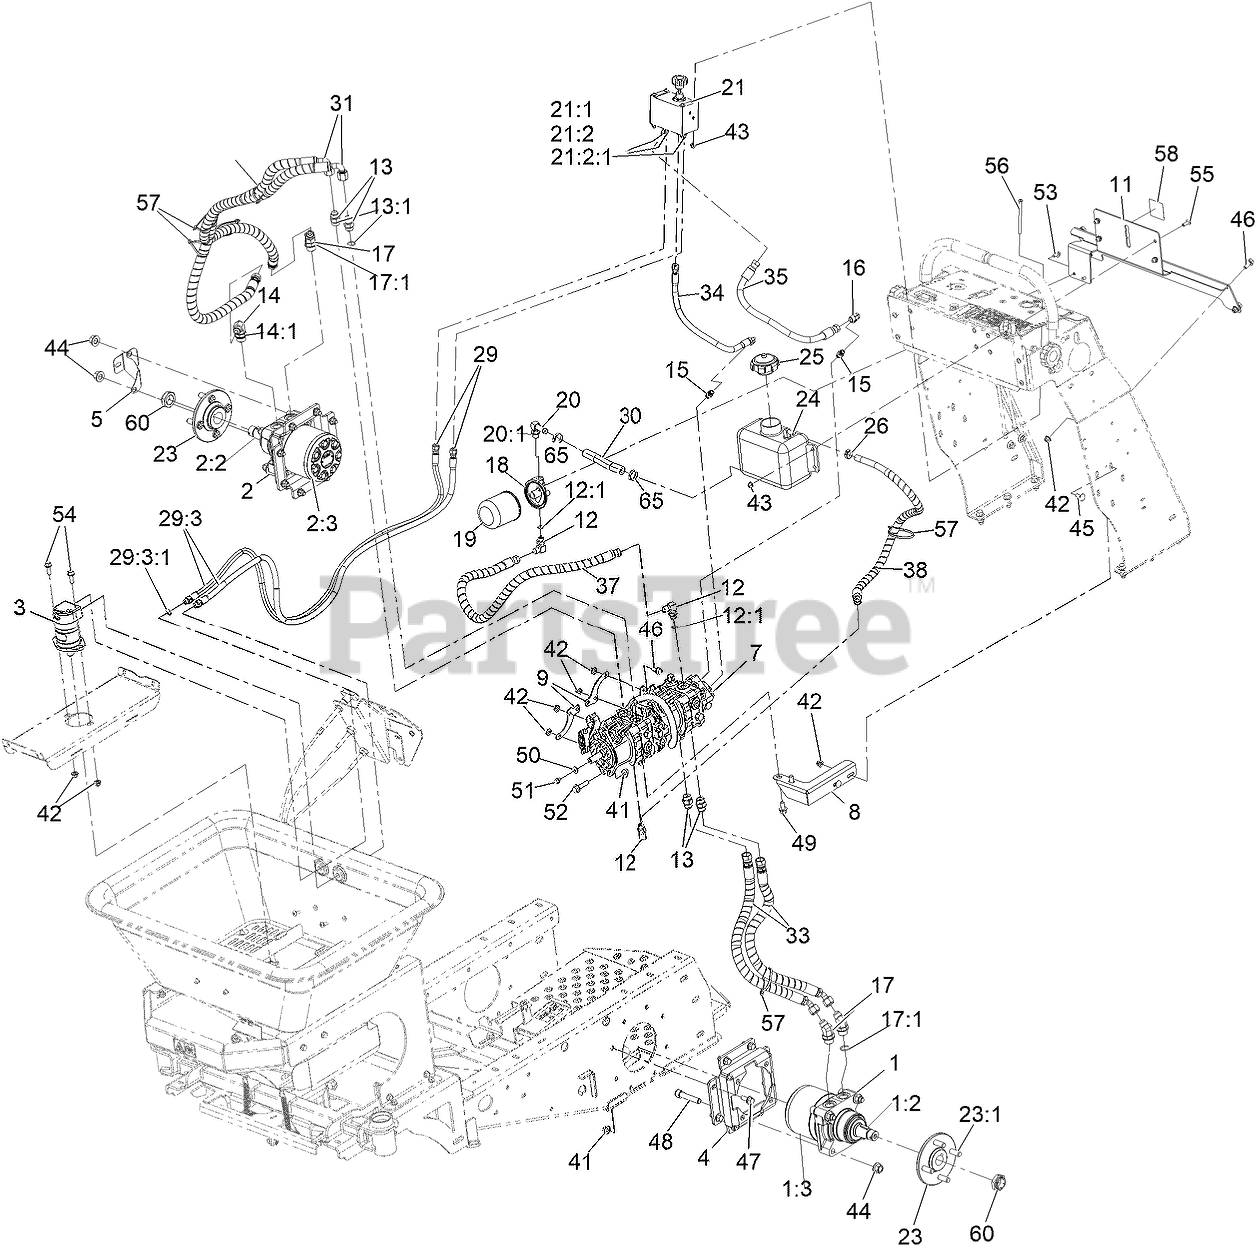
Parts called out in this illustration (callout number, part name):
1	MOTOR, LH WHEEL
1:2	KEY-WOODRUFF
1:3	SEAL KIT
2	MOTOR, RH WHEEL
2:2	KEY-WOODRUFF
2:3	SEAL KIT
3	MOTOR-HYDRAULIC, SPREADER
4	Mount-Motor, Wheel
5	BRACKET-HOPPER, SPEEDOMET
7	PUMP-TANDEM
8	Bracket-Support, Hydro Pump
9	Extension, Hydro Pump
11	Mount, Hydraulic Tank And Filter
12	FITTING-ELBOW, 90 DEG
12:1	O-RING
13	FITTING-STRAIGHT
13:1	O-RING
14	FITTING-90 DEG
14:1	O-RING
15	FITTING-STRAIGHT
16	FITTING-90 SWIVEL
17	FITTING-ELBOW, 45 DEG
17:1	O-RING
18	HEAD-FILTER
19	FILTER-25 MICRON, BI-DIRECTIONAL
20	FITTING-ELBOW, 90
20:1	O-RING
21	Manifold-Flow Control, Hopper
21:2	FITTING-ELBOW, 45 DEG
21:2:1	O-RING
23	HUB-WHEEL
23:1	STUD-1/2-20 X 1.55
24	TANK-HYDRAULIC, PLASTIC
25	Cap-Vented
26	CLAMP-OETIKER, 167
29	HOSE ASM-HYD HP
29:3	Fitting-Straight, Rigid
29:3:1	O-RING
30	HOSE-HYDRAULIC
31	HOSE ASM-HYD HP
33	HOSE ASM-HYD HP
34	Hose ASM-HYD HP
35	Hose ASM, HYD LP
37	Hose ASM, HYD LP
38	Hose ASM, HYD LP
41	Nut-Hex Flange
42	Nut-Hex Flange
43	Nut-Hex Flange
44	Nut-Lock 1/2-13
45	SCREW-CARR
46	SCREW-HHF
47	SCREW-HHF
48	Screw-HSH
49	SCREW-HHF
51	SCREW-HHF
52	SCREW-HHF
53	SCREW-HHF
54	SCREW-HHF
55	Screw-Hsbhf
56	Screw-HSBH
57	TIE-CABLE
58	DECAL-OIL
60	LOCKNUT
65	CLAMP-OETIKER, 167
